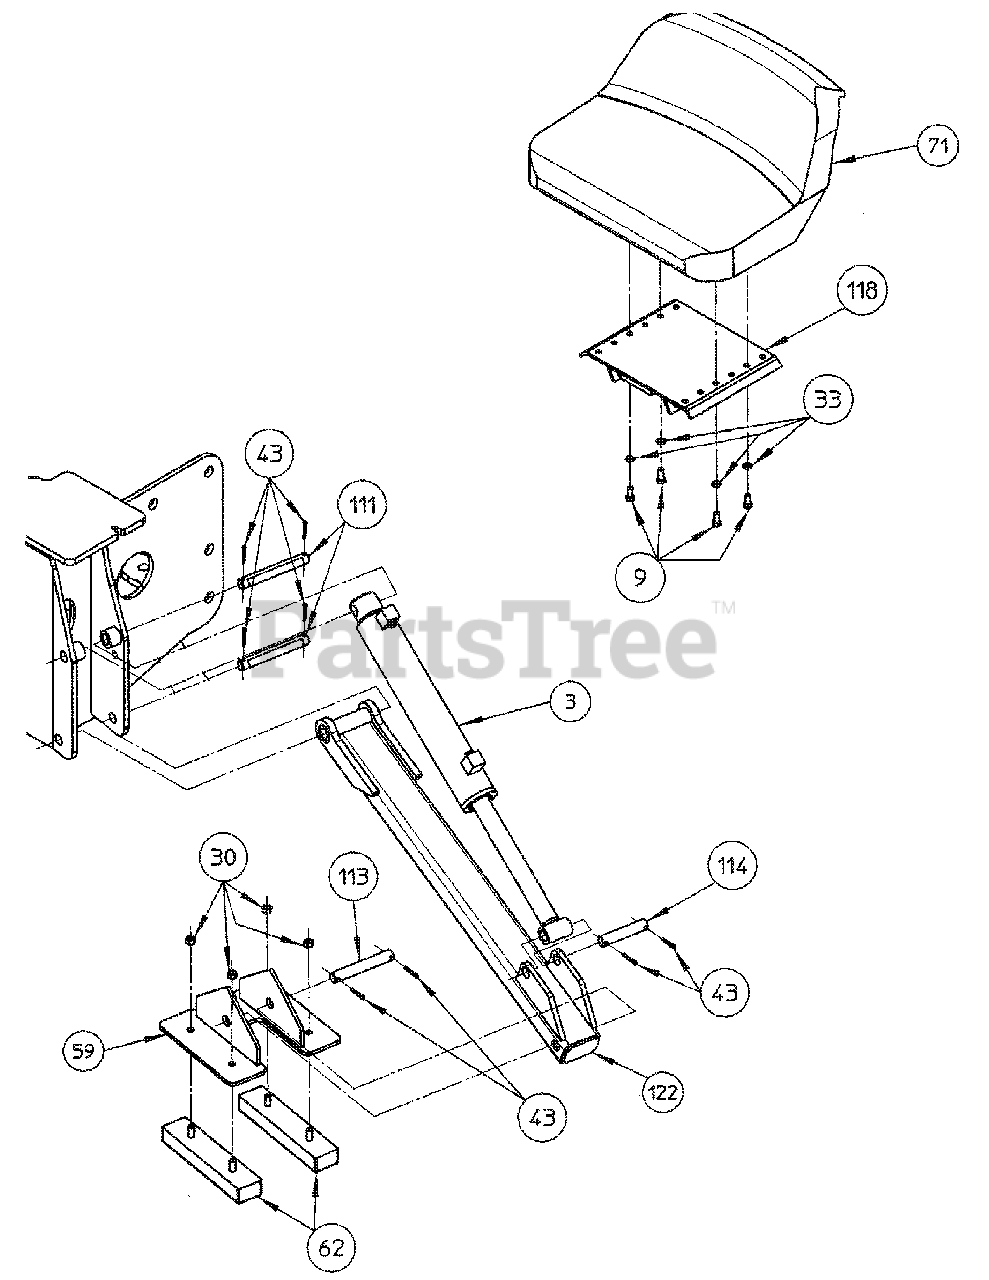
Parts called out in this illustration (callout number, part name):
1	Hydraulic Cylinder - Swing
2	Hydraulic Cylinder - Bucket
3	Hydraulic Cylinder - Stabilizer
4	Hydraulic Cylinder - Boom
5	Hydraulic Cylinder - Dipper
6	Bolt, Carriage 5/16 NC x 3/4"
7	Bolt, Carriage 5/16 NC x 1-1/4"
8	Bolt, 1/4 NC x 3/4"
9	Bolt, 5/16 NC x 3/4"
10	Bolt, 5/16 NC x 3/4" Thread Forming
11	Bolt, 5/16 NF x 3/4"
12	Bolt, 5/16 NF x 7/8"
13	Bolt, 5/16 NF x 1" Gr. 5
14	Bolt, 5/16 NF x 2-1/4" Gr. 5
15	Bolt, 5/16 NF x 2-1/2" Gr.5
16	Bolt, 5/16 NF x 4" Gr. 8
17	Bolt, 3/8 NF x 3/4"
18	Bolt, 3/8 NF x 1"
19	Bolt, 3/8 NF x 1-1/4"
20	Bolt, 3/8 NF x 1-3/4"
21	Bolt, 3/8 NF x 2-1/4"
22	Bolt, 3/8 NF x 2-3/4"
23	Bolt, 3/8 NC x 5-1/2" Long Gr.5
24	Bolt, 1/2 NF x 7/8"
25	Nut, 1/4 NC
26	Nut, 5/16NC
27	Locknut, 5/16 NC
28	Nut, 5/16 NF
29	Locknut, 5/16 NF
30	Lock Nut, 3/8NC
31	Locknut, 3/8 NF
32	Lockwasher, 1/4
33	Lockwasher, 5/16
34	Flat Washer. 5/16 STD
35	Washer, 5/16 SAE
36	Flat Washer, 3/8 SAE
37	Flat Washer, 1/2" Hardened
38	Machine Bushing, 1-1/4 OD x 3/4 ID x 14Ga.
39	Machine Bushing 1-1/2" OD x 1" ID x 18Ga.
40	Machine Bushing 1-7/8" OD x 1-1/4" ID x 18Ga.
41	Machine Bushing, 2-1/2 OD x 1-3/4ID x 18Ga
42	Cotter Pin, 3/32" Dia x 3/4"
43	Cotter Pin, 3/16 x 1-1/4"
44	Cotter Pin, 1/4 x 1-1/2"
45	Hair Pin Cotter, 3/64" Dia x 11/16"
47	Adapter Union, 9/16-18M x 3/8NPTF
48	Hydraulic Tee
49	Adapter Union, 3/4-16M x 3/8NPTF x Straight
50	Adapter Union, 3/8NPTM x 3/8NPTF x 90 degree
51	Adapter Union, 9/16-18M x 3/8NPTF x 90 degree
52	Adapter Union, 7/8-14M x 3/8 NPTF x 90 degree
53	Adapter Union, 3/4-16M x 3/8NPTF x 90 degree
54	Coupler Body 3/4-16F Thread
55	Coupler Nose 3/4-16F Thread
56	Garlock Bearing, 028DXR020
57	Bronze Bearing
58	Garlock Bearing, 028DXR016
59	Stabilizer Pad Weldment
60	Guide Link
61	Bucket Link
62	Street Pad
63	Clevis Pin, 3/16" Dia x 5/8"
64	Clevis Pin, 1/4" Dia x 7/8"
65	Pin Retainer
66	Pin Retainer
67	Boom Lock Pin
68	Swing Lock Pin
69	SMV Socket
70	SMV Bracket
72	Ball Joint - Shouldered
73	Ball Joint
74	Control Knob
75	Rubber Cap
76	Plastic Tie T150L
77	Plastic Tie T120 L
78	Plastic Tie T50L
80	Hose Sleeve FC425-16 X 30" Long
81	Hose Sleeve FC425-16 X 19" Long
82	Hose Sleeve FC425-16 X 48" Long
83	Hose Sleeve FC425-16 X 63" Long
84	Hose Sleeve FC425-16 X 79" Long
85	Grease Fitting
86	Grease Fitting (Two are part of #000187 Cyl.)
87	Grease Fitting (Two are part of #000187 Cyl.)
88	Hydraulic Hose, 3/8NPTM x 3/8NPTM x 20" long
89	Hydraulic Hose, 3/8NPTM x 3/8NPTM x 23" long
90	Hydraulic Hose, 3/8NPTM x 3/8NPTM x 30" long
91	Hydraulic Hose, 3/8NPTM x 3/8NPTM x 58" long
92	Hydraulic Hose, 3/8NPTM x 3/8NPTM x 76" long
93	Hydraulic Hose, 3/8NPTM x 3/8NPTM x 92" long
94	Hydraulic Hose, 3/8NPTM x 3/8NPTM x 110" long
95	Hyd. Hose, 3/8ID 3/8NPTF M x 3/4-16 Str O x 49"
96	Hyd. Hose, 3/8ID 3/8NPTF M x 3/4-16 Str O x 34"
97	Control Valve
98	Adapter Union, 7/16-20M x 3/8NPTF
99	Rear Shroud
100	Stabilizer Lever Control Rods
101	Control Rod
102	Pivot Pin, Boom Cyl. Rod 1-1/4" Dia. x 6" Long
103	Thrust Washer
104	Pivot Pin, Bucket 1"Dia. x 7-3/8" Long
105	SMV Socket Mount
106	Stabilizer Control Lever
107	Lever Bracket
108	Hose Clamp - Short
109	Pivot Pin, 3/4" Diameter x 4-1/16" Long
110	Pivot Pin, Dipperstick 1-1/4" Dia. x 7-15/16" Long
111	Pivot Pin, Stabilizer Leg
112	Pivot Pin Weldment
113	Pivot Pin, Stabilizer Pad 3/4" Dia. x 4-15/16" Long
114	Pivot Pin, Stabilizer Cyl. Rod
115	Pivot Pin, Bucket Cyl. Base 1" Dia. x 5-7/8" Long
116	Pivot Pin, Boom Cyl. Base 1-1/4" Dia. x 7-1/4" Long
117	Lower Pivot Pin Weldment
118	Seat Plate Weldment
119	RH Pivot Weldment
120	LH Pivot Weldment
122	Stabilizer Leg Weldment
123	Upper Pivot Pin Weldment
124	Pivot Pin Weldment, Boom 1-3/4" Dia. X 2-3/4" Lg
125	RH Toe Shield
126	LH Toe Shield
127	Hose Clamp - Long
128	Grab Bar Weldment
129	Mainframe Weldment
130	Valve Mount Weldment
131	Swing Frame Weldment
132	Front Shroud Weldment with Decals
133	Dipperstick Weldment
134	Boom Weldment
135	Right Hand Joystick Weldment
136	Left Hand Joystick Weldment
